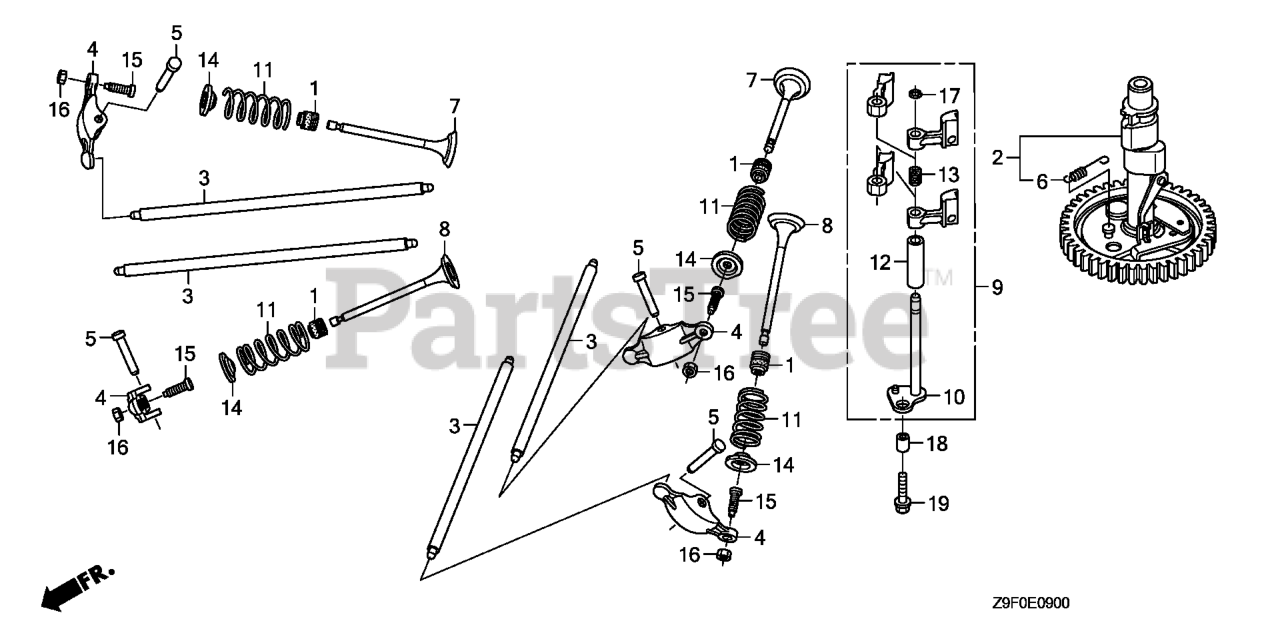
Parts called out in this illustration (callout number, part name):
1	SEAL, VALVE STEM
2	CAMSHAFT ASSY.
4	ARM, VALVE ROCKER
5	SHAFT, ROCKER ARM
6	SPRING, WEIGHT RETURN
7	VALVE, IN.
8	VALVE, EX.
9	LIFTER ASSY., VALVE
10	SHAFT, VALVE LIFTER
11	SPRING, VALVE
12	COLLAR, VALVE LIFTER
13	SPRING, VALVE LIFTER
14	RETAINER, IN. VALVE SPRING
14	RETAINER, VALVE SPRING (EXHAUST SIDE)
15	SCREW, TAPPET ADJUSTING
16	NUT, TAPPET ADJUSTING
17	CLIP, GOVERNOR HOLDER
18	PIN, DOWEL (8X10)
19	BOLT, FLANGE (6X22)
